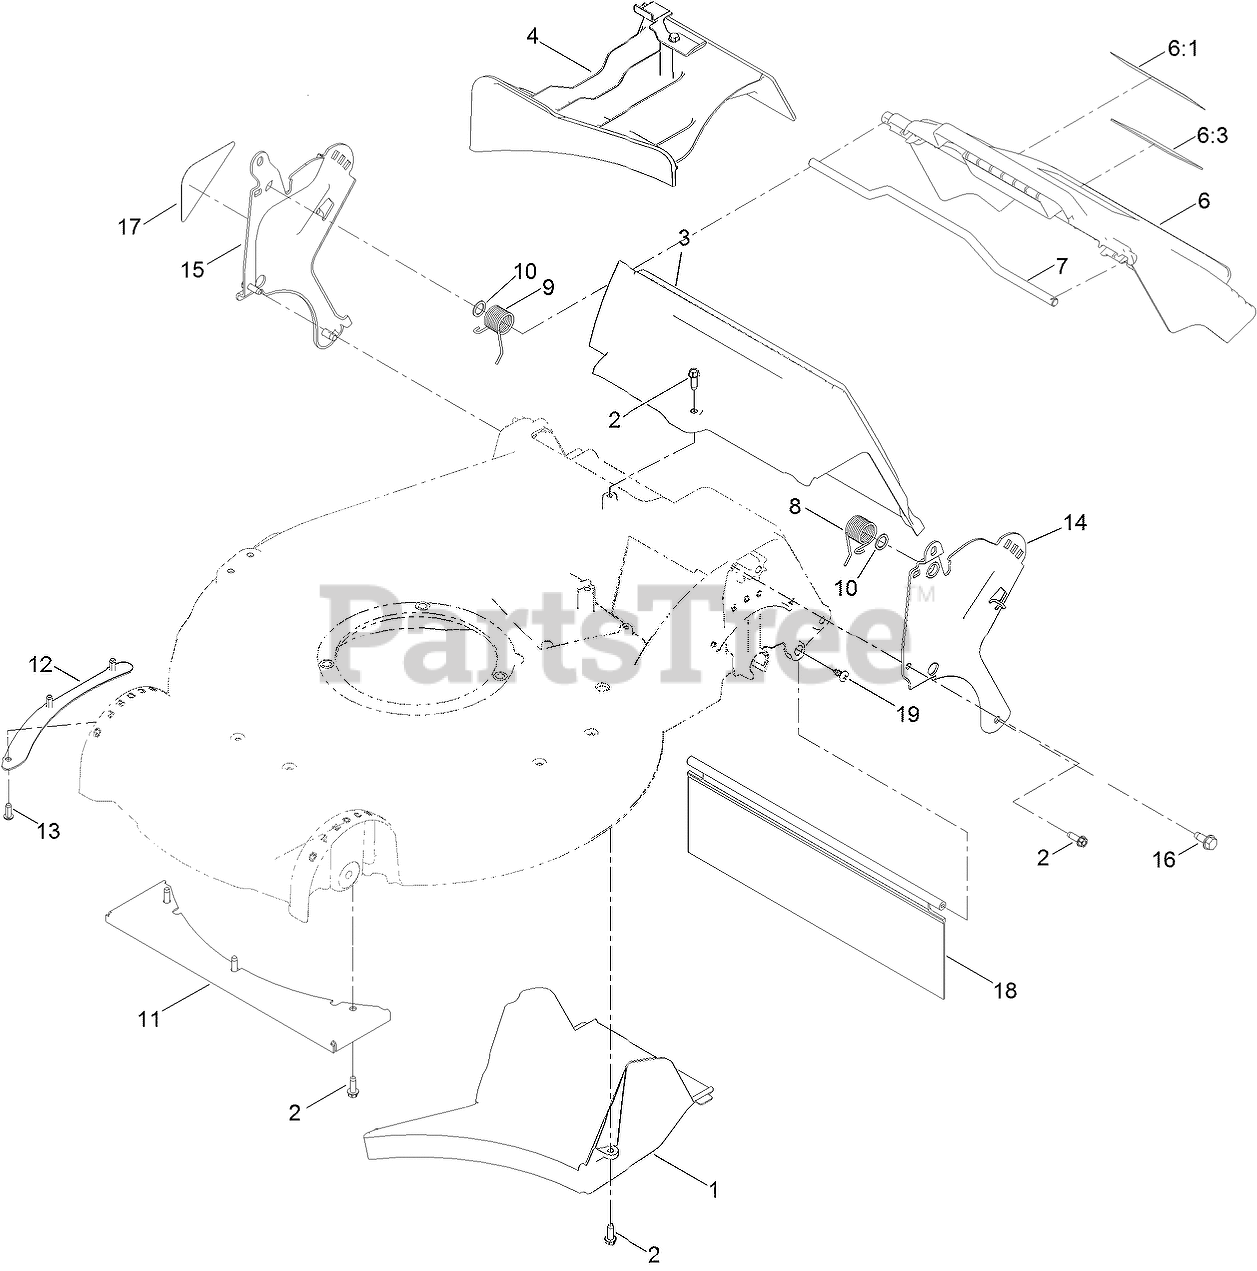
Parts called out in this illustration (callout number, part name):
1	TUNNEL-DISCHARGE
2	SCREW-HWHTF
4	MULCH PLUG ASM
6	REAR DOOR ASM
6:1	DECAL-WARNING
6:3	DECAL-WARNING
7	ROD-DEFLECTOR
8	SPRING-TORSION
9	SPRING-TORSION
10	WASHER-NYLON
11	PLATE-COVER, FRONT
12	SHEET-LIP
13	SCREW
14	BRACKET-HANDLE, LH
15	BRACKET-HANDLE, RH
16	SCREW-HWHTF
17	DECAL-INSTRUCTION
18	SHIELD-TRAILING
19	SCREW-THD
